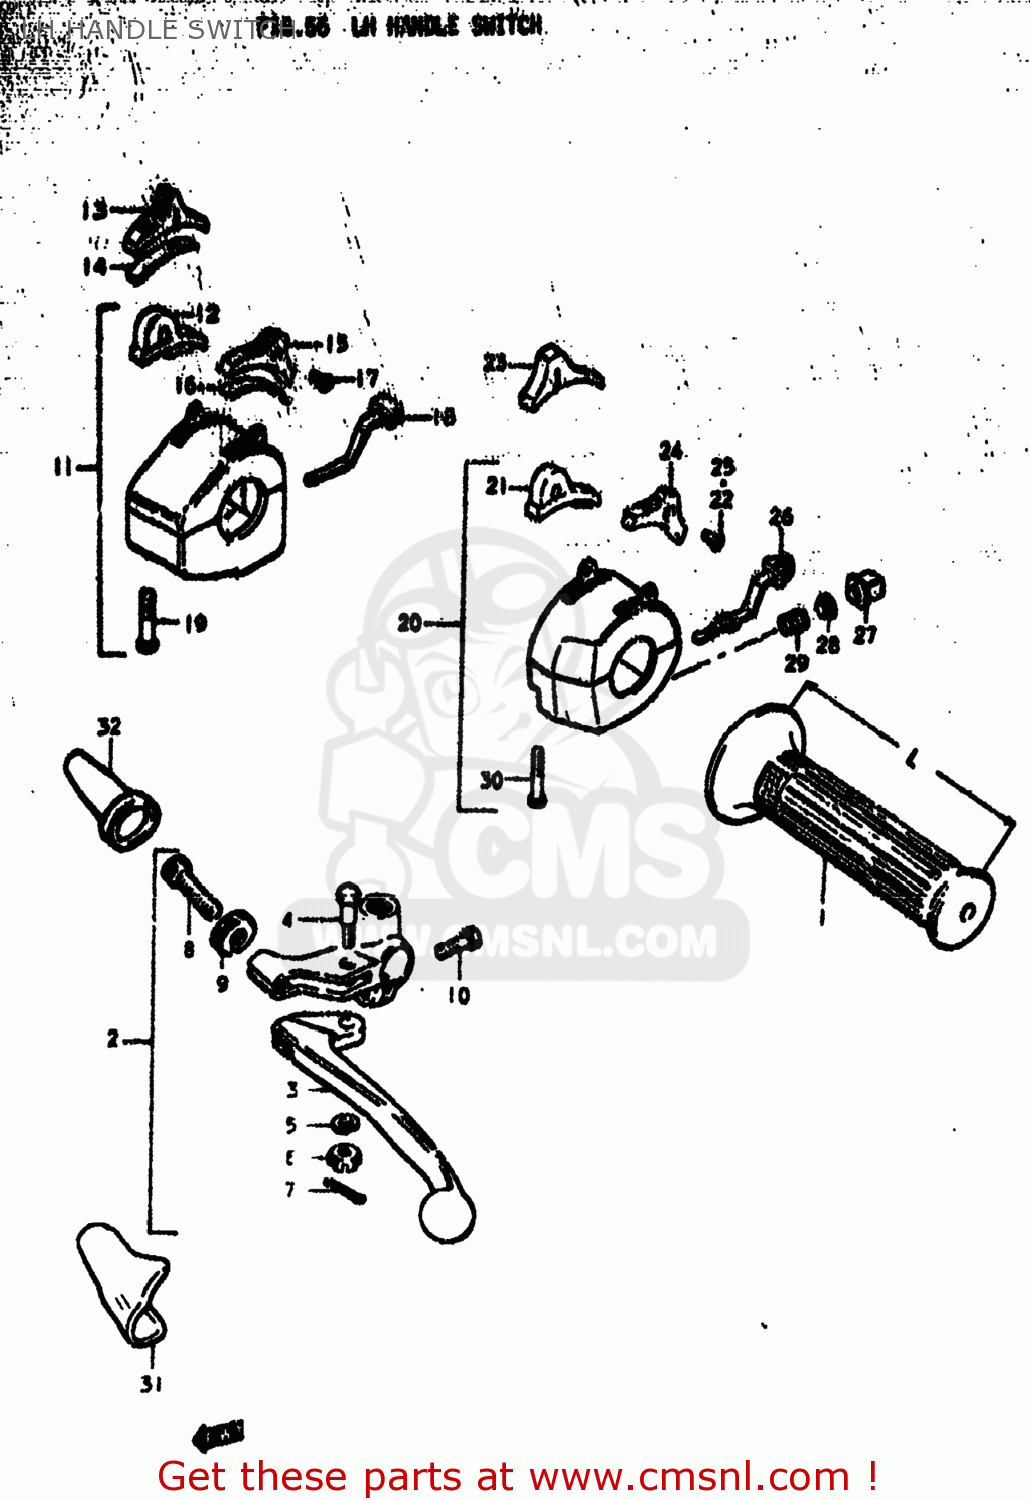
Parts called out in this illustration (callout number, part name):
1	GRIP,LEFT
2	LEVER ASSEMBLY
3	LEVER,CLUTCH
4	BOLT,LEVER
5	LOCK WASHER
6	NUT 6MM
7	COTTER PIN
8	ADJUSTER,CABLE
9	NUT,CABLE ADJUSTER
10	BOLT
11	SWITCH ASSEMBLY,HANDLE,LEFT
13	KNOB,HANDLE SWITCH
14	PLATE,SWITCH KNOB
15	KNOB,HANDLE SWITCH
16	PLATE,SWITCH KNOB
17	SCREW
18	KNOB,TURN SIGNAL SWITCH
19	SCREW
20	SWITCH ASSEMBLY,HANDLE,LEFT
21	KNOB,STOP
22	SCREW
23	KNOB,LIGHTING SWITCH
24	KNOB,DIMMER SWITCH
25	SCREW
26	KNOB,TURNSIGNAL
27	BUTTON,HORN
28	CONTACT
29	SPRING
30	SCREW
31	COVER,CLUTCH LEVER
32	BOOT,CLUTCH CABLE
